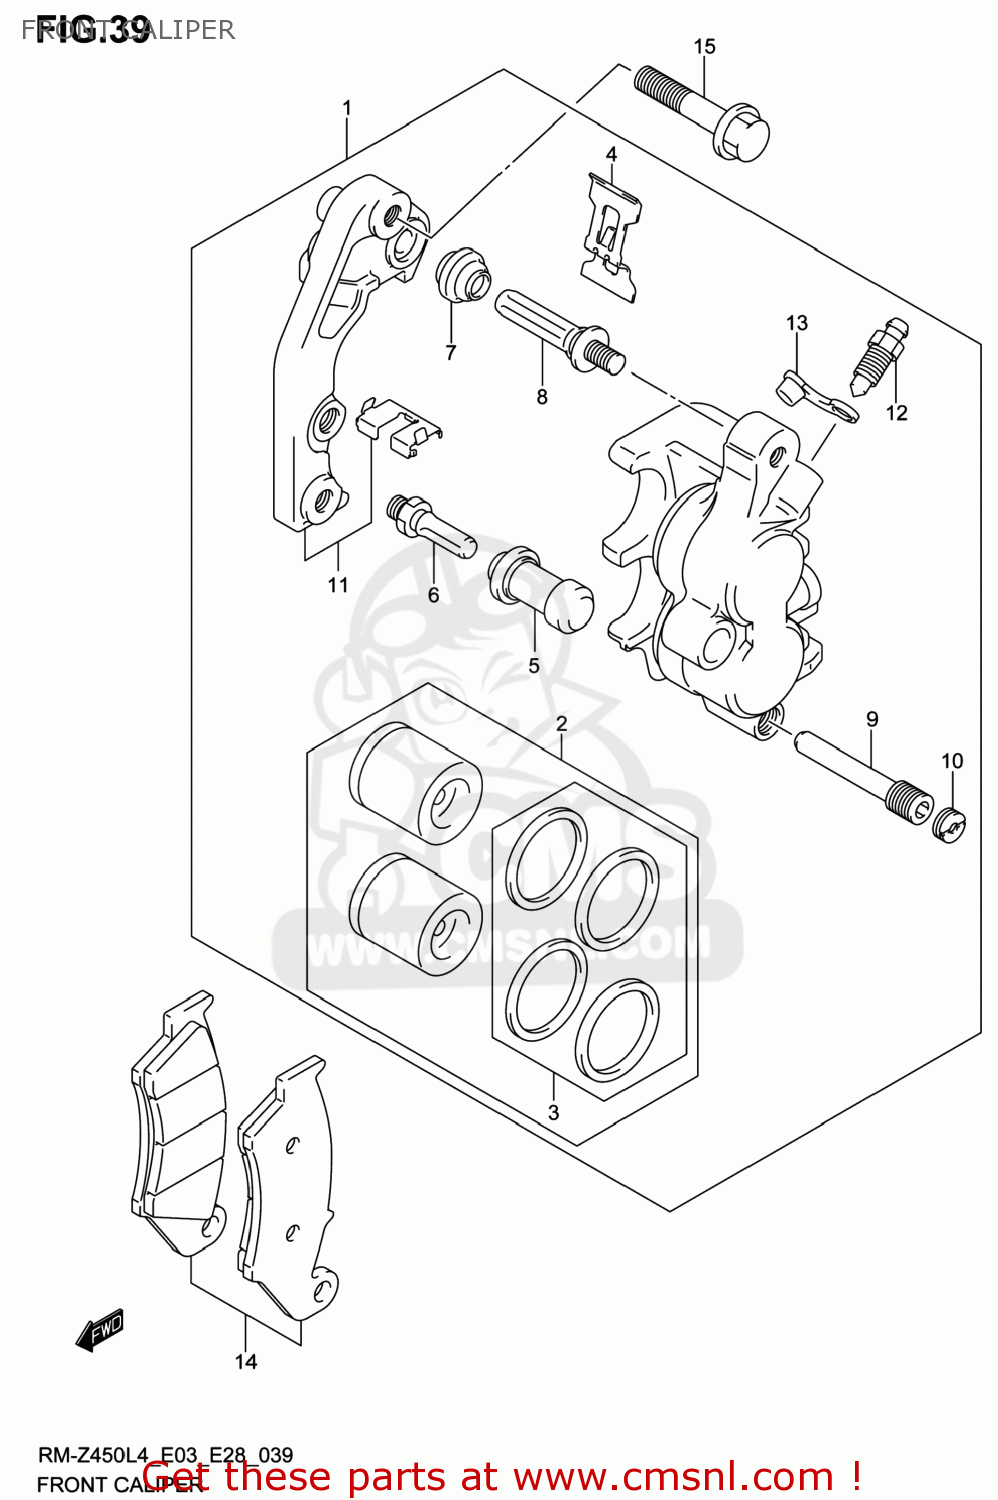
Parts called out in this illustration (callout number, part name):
1	CALIPER ASSY,FR
2	PISTON SET
3	SEAL SET,PISTON
4	SPRING,PAD
5	BOOT
6	BOLT
7	BOOT
8	PIN
9	PIN,HANGER
10	PLUG,PIN
11	BRACKET
12	BLEEDER
13	CAP,BLEEDER
14	PAD SET (NAS)
15	BOLT(8X41)
